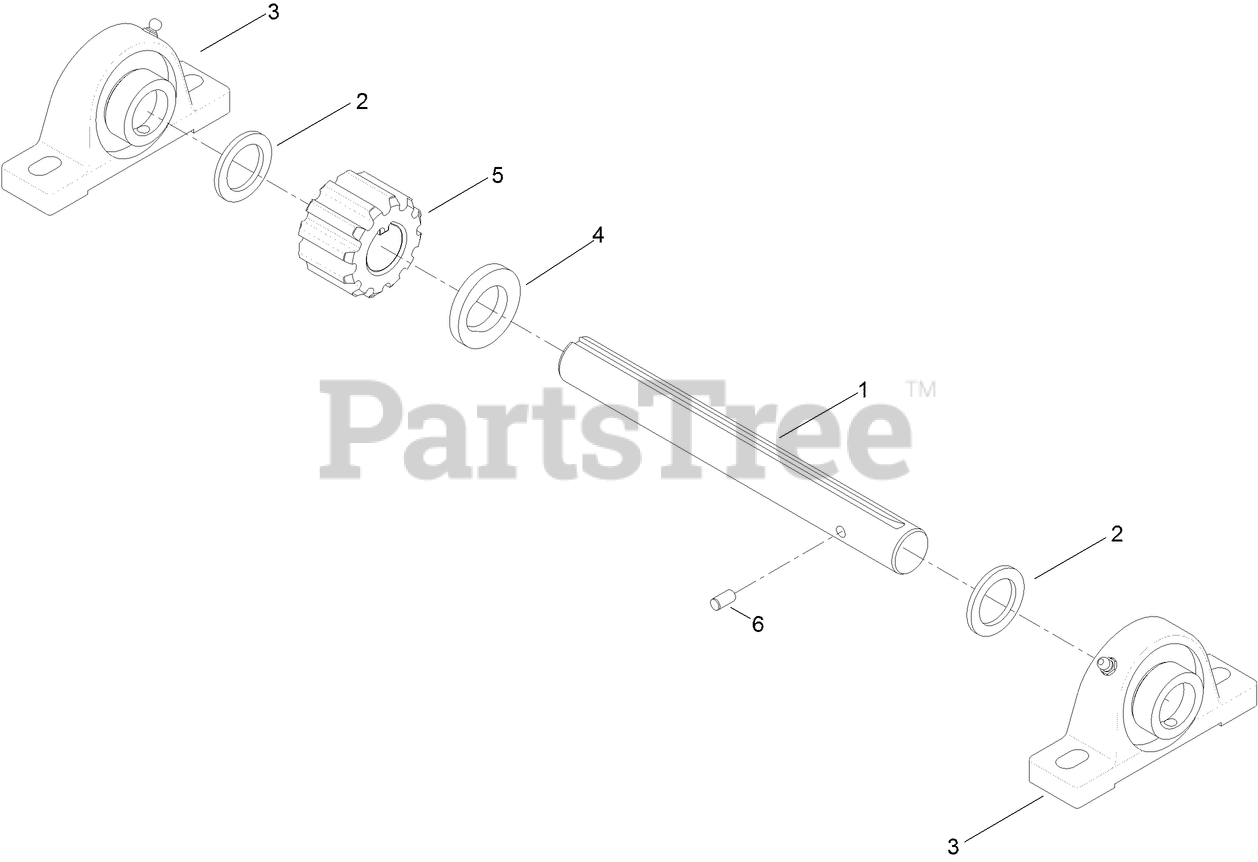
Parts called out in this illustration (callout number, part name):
1	SHAFT-PINION
2	WASHER-THRUST
3	BEARING-BLOCK, PILLOW
4	WASHER
5	GEAR-SPUR
6	PIN-DOWEL
